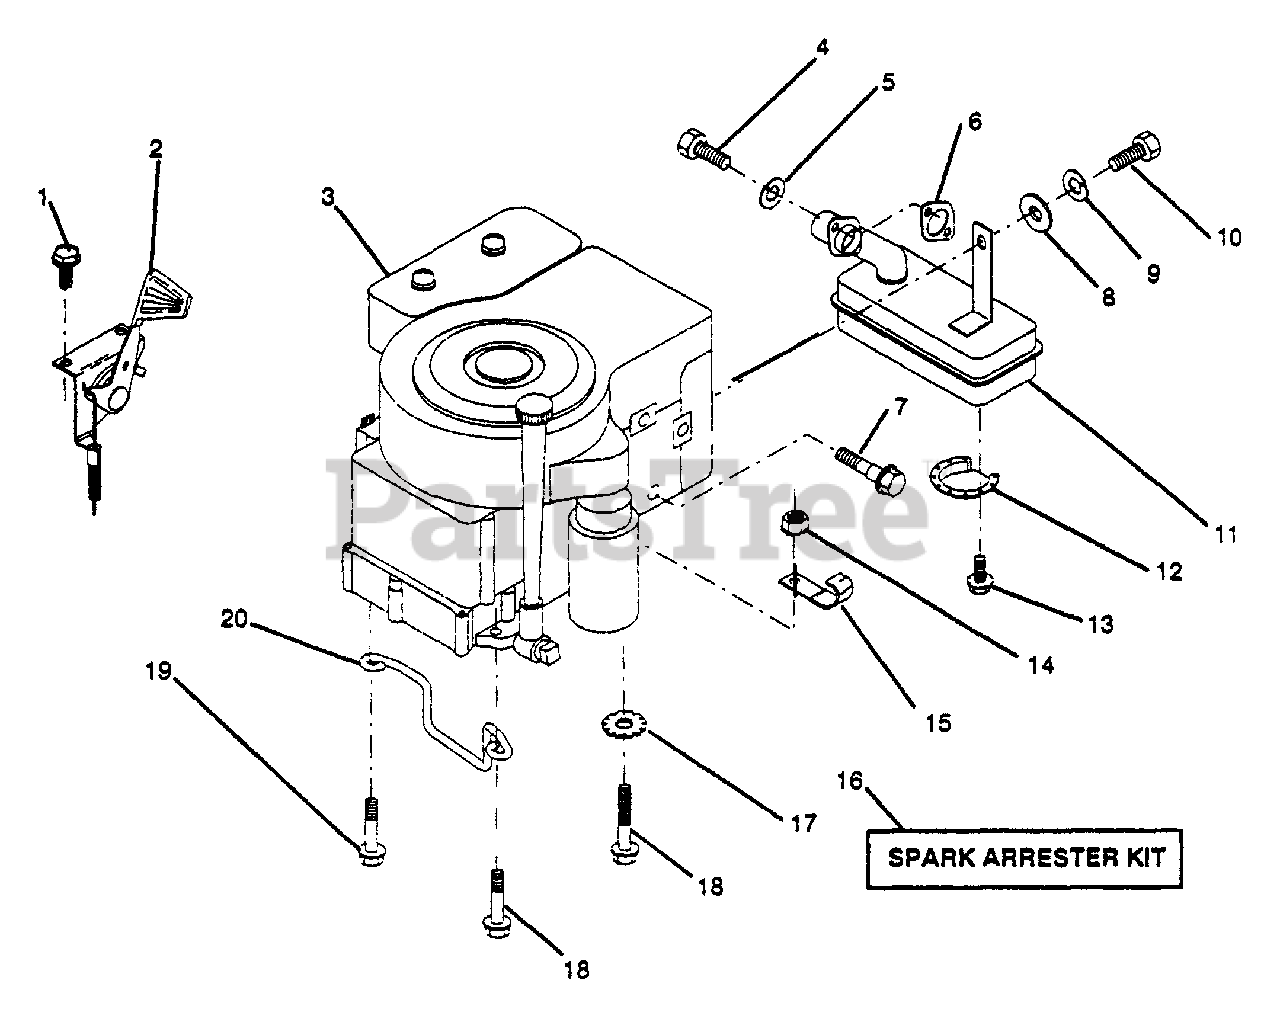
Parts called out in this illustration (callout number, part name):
1	Screw, Hex Thd. Cut 1/4-20 x 1/2
2	Control, Throttle
3	Engine, Briggs and Stratton
4	Screw, Hex Hd Cap 5/16--18 x 3/4
5	Washer, Lock Heavy Helical Spring 5/16
6	Gasket, Exhaust
7	Bolt, Shoulder 5/16
8	Washer 5/16 x 3/4 x 16 Ga.
9	Washer, Lock Heavy Helical Spring 1/4
10	Soft, Hex Fin. 1/4-20 UNC x 3/4
11	Muffler
12	Deflector, Muffler
13	Screw, Spiderlock Hex #8 x 1/2 ABTPS
14	Nut, Keps 3/8-16
15	Clip, Fuel Line
16	Arrester, Spark
17	Washer, Lock, Ext. Tooth 3/8
18	Screw, Hex Wsh Hd Thdrol 3/8-16 x 2
19	Screw, Hex Wsh Hd Thdrol 3/8-16 x 1-1/2
20	Keeper, Ground Drive Belt
